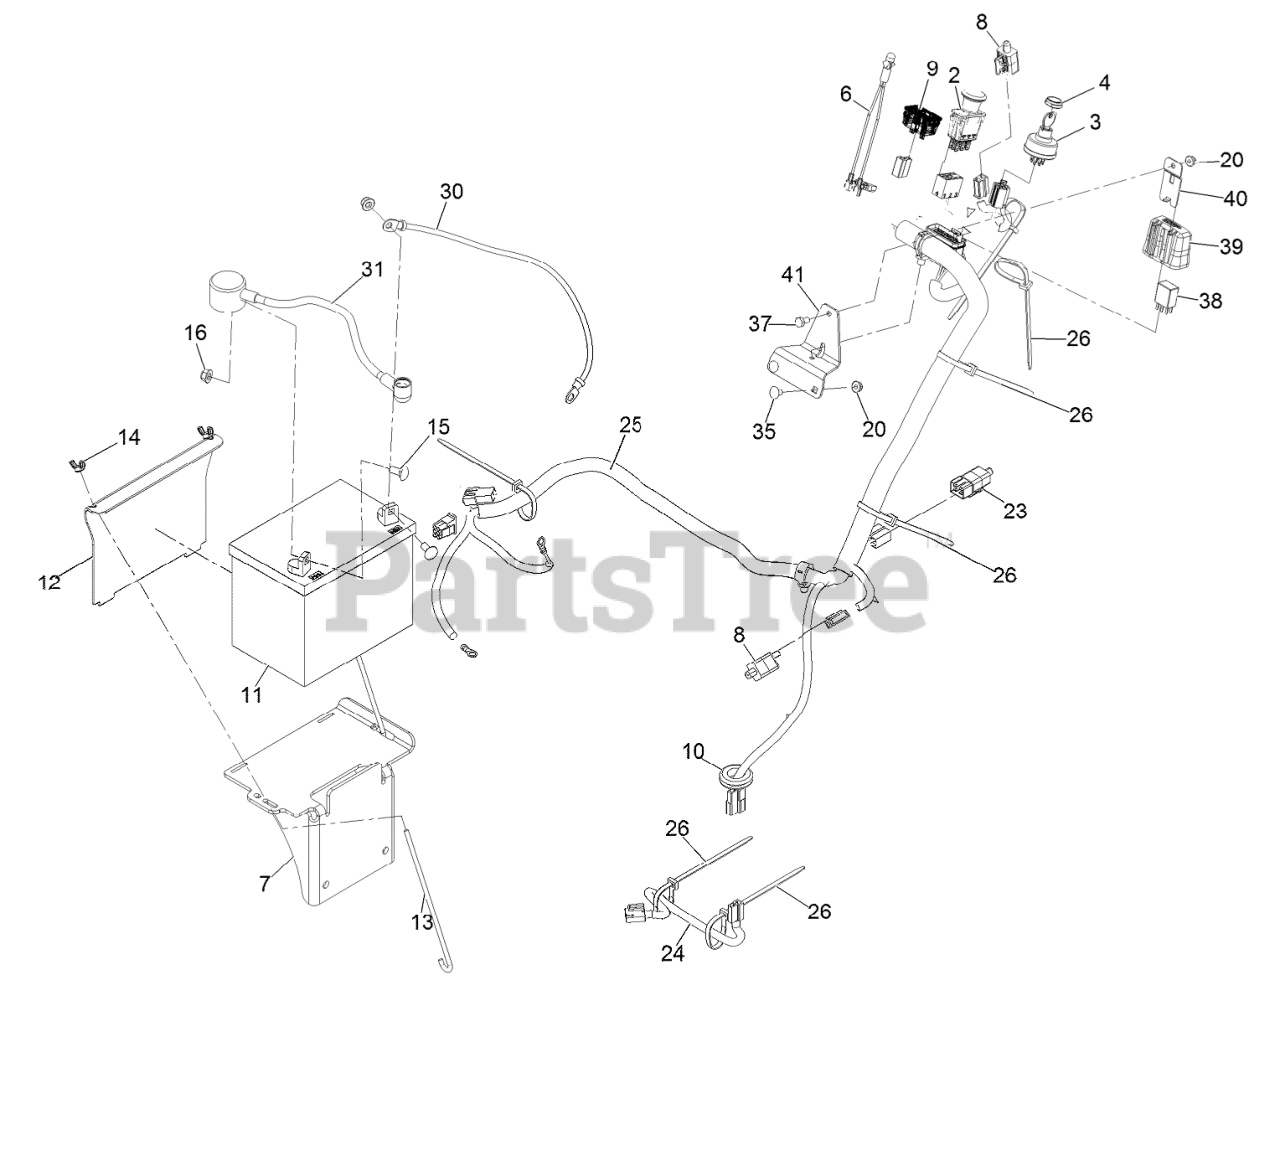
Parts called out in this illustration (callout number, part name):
2	SWITCH-PTO
3	SWITCH, KEY START
4	NUT-SWITCH, IGNITION
6	INDICATOR-LED, RED
7	WELD, BATTERY MOUNT
9	METER-HOUR
10	GROMMET
11	Battery
12	BRACKET, BATTERY HOLD DOW
13	BOLT-HOLDDOWN
14	WINGNUT
15	BOLT-CARR
16	NUT-HF, NI
23	SWITCH, 2 POLE
24	HARNESS-CLUTCH PIGTAIL
25	HARNESS-WIRING
26	TIE-PLASTIC
31	ASM,POSITIVE BATTERY CABL
35	SCREW-CARR
37	SCREW-HH
38	RELAY-MICRO 280, SPDT
39	COVER-BLOCK, FUSE
40	CLIP-MOUNTING
41	BRACKET-MOUNTING, FUSEBLO
